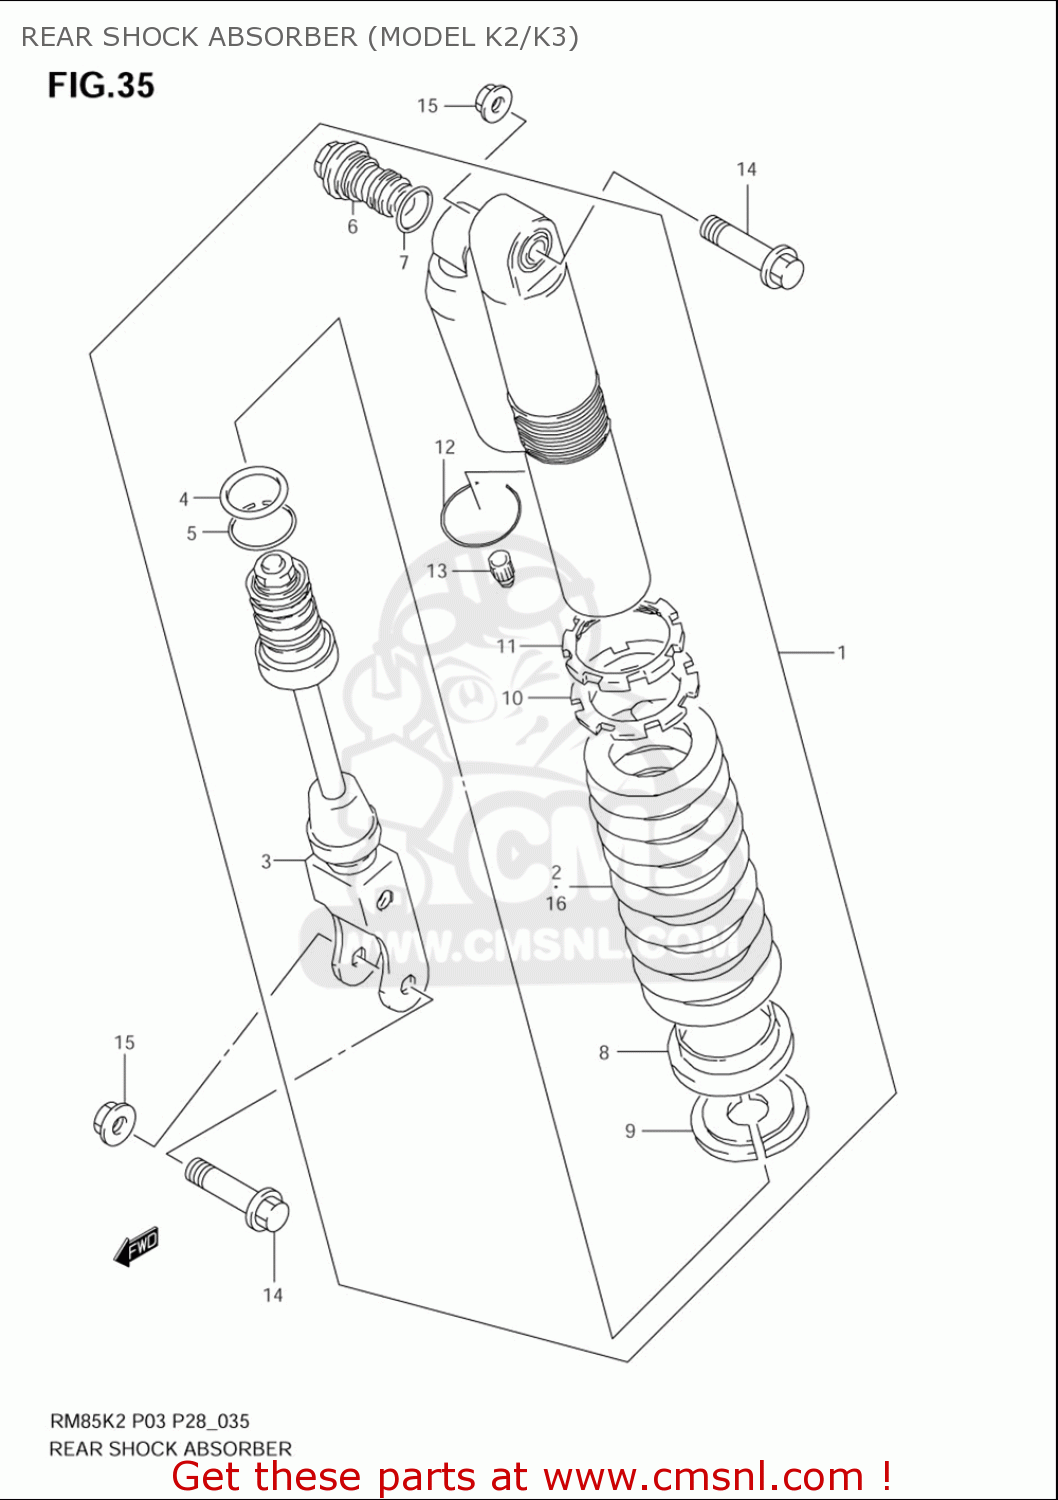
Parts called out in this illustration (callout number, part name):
1	ABSORBER ASSY,RR SHOCK
2	SPRING,RR(K=4.9)
3	ROD,PISTON
4	O RING
5	RING,STOPPER
6	BOLT,PLUG
7	O RING
8	SEAT,SPRING
9	SEAT,SPRING STOPPER
12	RING,STOPPER
13	CAP
14	BOLT,RR CUSHION ROD UPR
15	NUT
16	SPRING(SOFT)
